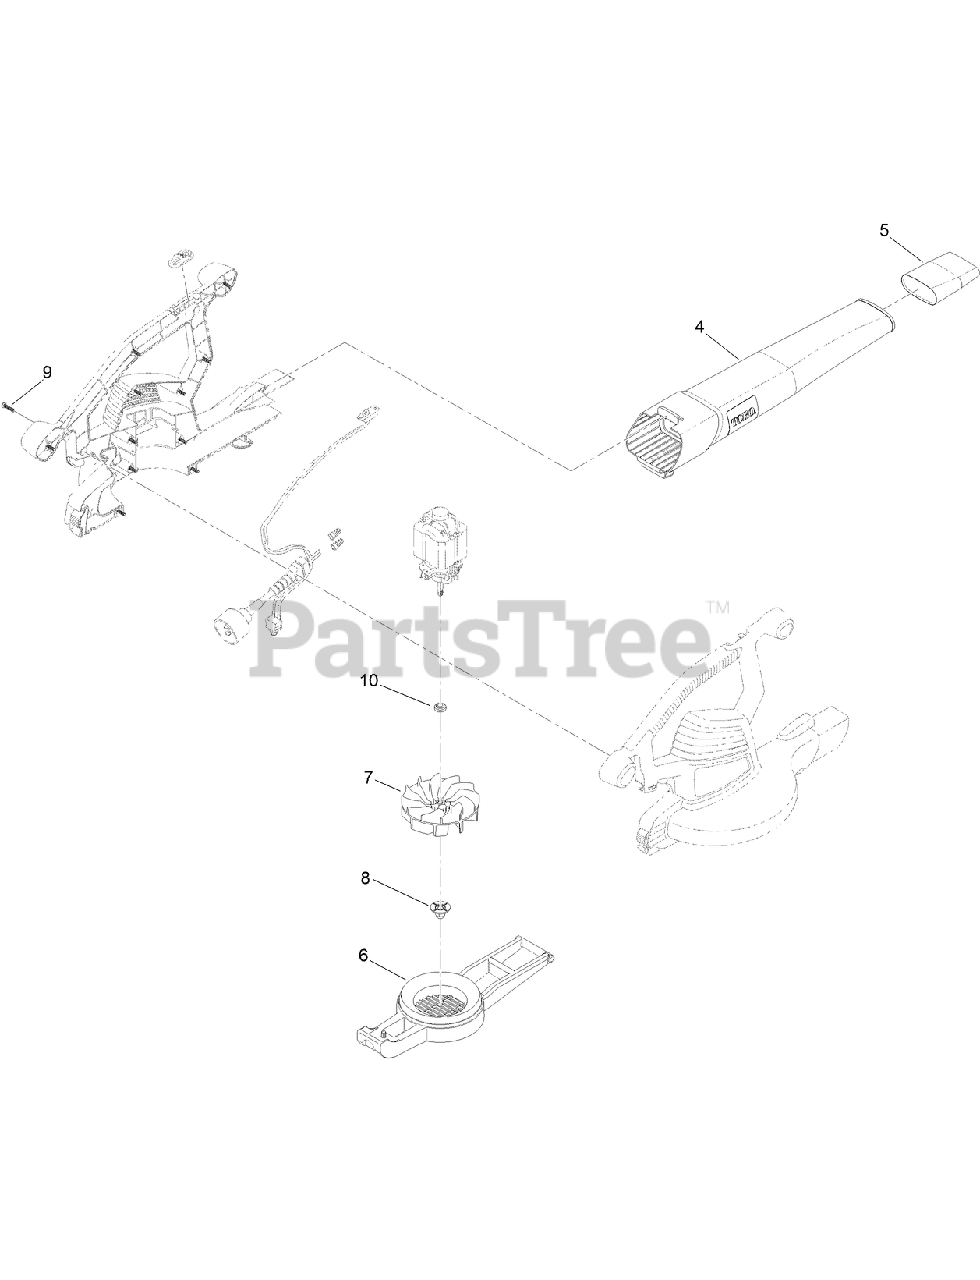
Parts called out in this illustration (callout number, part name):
4	TUBE-BLOWER
5	TUBE-INSERT, SUPER
6	COVER-INLET
8	NUT-IMPELLER
9	SCREW-PPH
10	BUSHING-MOTOR
